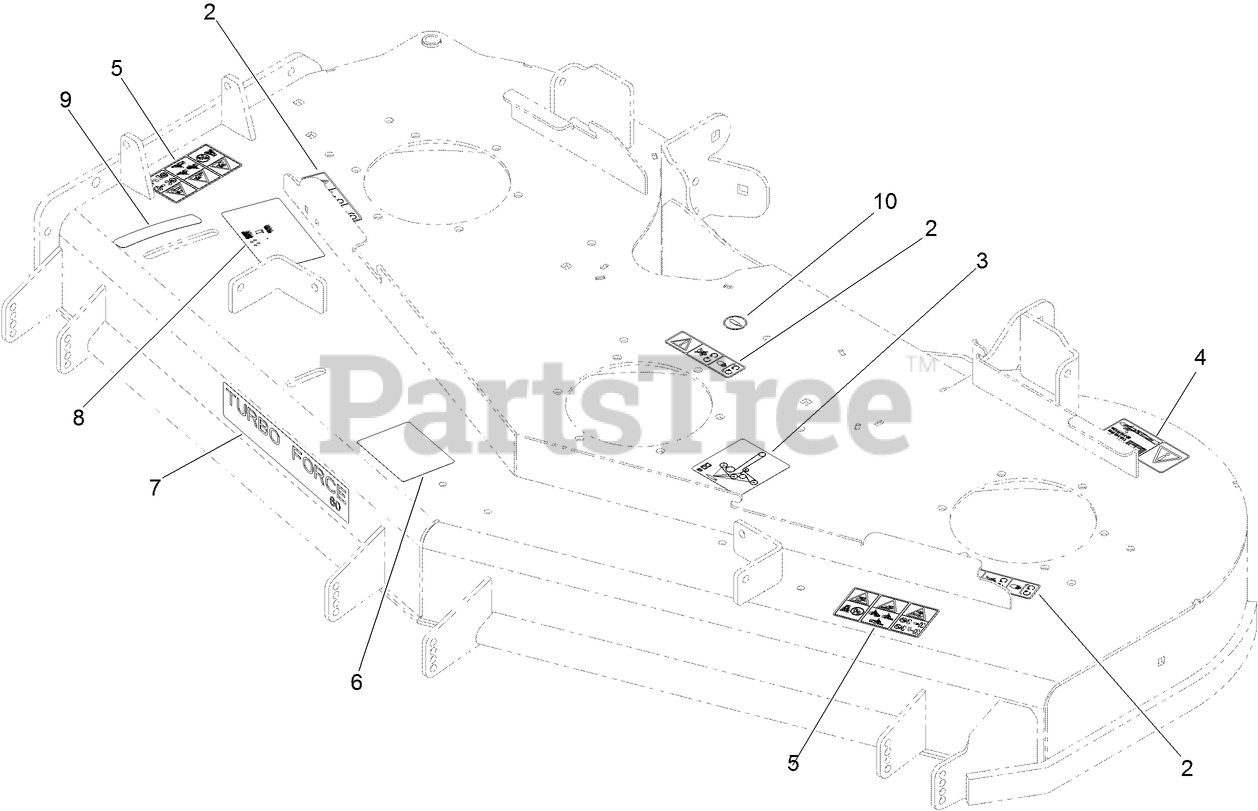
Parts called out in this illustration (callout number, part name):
2	DECAL-MISSING, COVER
3	DECAL-ROUTING, DECK BELT
4	DECAL-TORQUE, BLADE BOLT
5	DECAL-DANGER
6	DECAL-ANTI SCALP
8	DECAL-ADJUSTMENT, BAFFLE
9	DECAL-SETTING, BAFFLE
10	DECAL-GREASE
